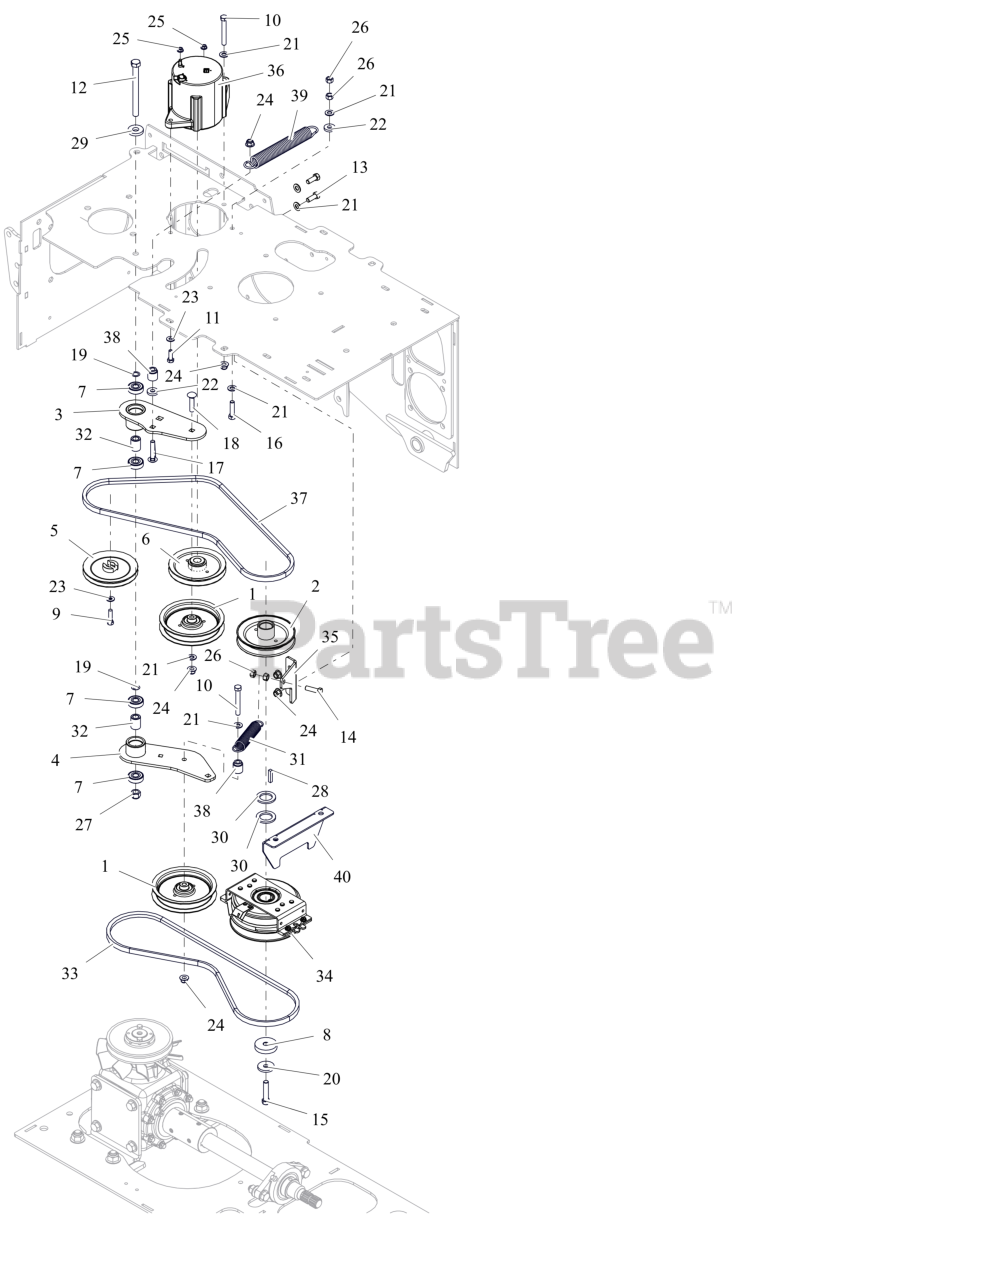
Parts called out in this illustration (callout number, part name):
1	IDLER- FLAT-5.00X.75
2	SHEAVE, ENGINE 1.127 ID X 5.250 OD
3	WLDMT- IDLER ARM
4	WLDMT- IDLER ARM
5	PULLEY- PUMP
6	PULLEY- SPLIT V
7	BRG-BALL .500X1.38X.437
8	SPACER, .450X2.00X.396
9	@BLT-HEX .31-24X1.25 GR5 YWZC
10	BLT, HEX .38-16X2.75 G5 ZCC
11	BLT,HEX M8-1.25X25 G8.8 ZC120
12	BLT,HEX .50-13X5.50 G5 ZCC
13	BLT,HEX .38-16X1.00 G5 ZCC
14	BLT, HEX .38-16X1.25 G5 ZCC
15	BLT, HEX .44-20X2.00 G8 ZCC NT
16	BLT, HEX .38-16X1.50 G5 ZCC
17	BLT, RHSN .38-16X2.00 G5 ZCC
18	BLT, RHSN .38-16X1.75 G5 ZCC
19	WASHER, .500X.750X.020 THRUST
20	WASHER, 7/16" SPRING DISK
21	WSHR,FLT .406X.812X.065 ZCC
22	WSHR, FLT .406X1.00X.188 ZCC
23	WSHR, FLT .312X.734X.065 ZCC
24	NUT,NYL-FLG .38-16 GF ZCC
25	NUT- SPNLK-FLG M6-1.0 G8.8 ZCC
26	NUT-LK-CTR .38-16 ZC120
27	NUT,NYL .50-13 G5 ZCC
28	KEY-SQ .25 X 1.25 X .25 SAE
29	WSHR- 1.375X.563X.250
30	WSHR- 1.750 X 1.350 X .134
31	SG-TENS .105X1.00X5.0
32	SPACER .510 X .75 X 1.1485
33	BELT- PTO - HA
34	CLUTCH, OGURA GT2.75-DC03(D)
35	BRKT- SPRING/CABLE
36	ELEC- POWER ALTERNATOR 70A
37	BELT- HYDRO - HA
38	SPCR- BSHG - SPRING ANCHOR
39	SPRG- EXTENSION
40	PLATE- CLUTCH STOP
